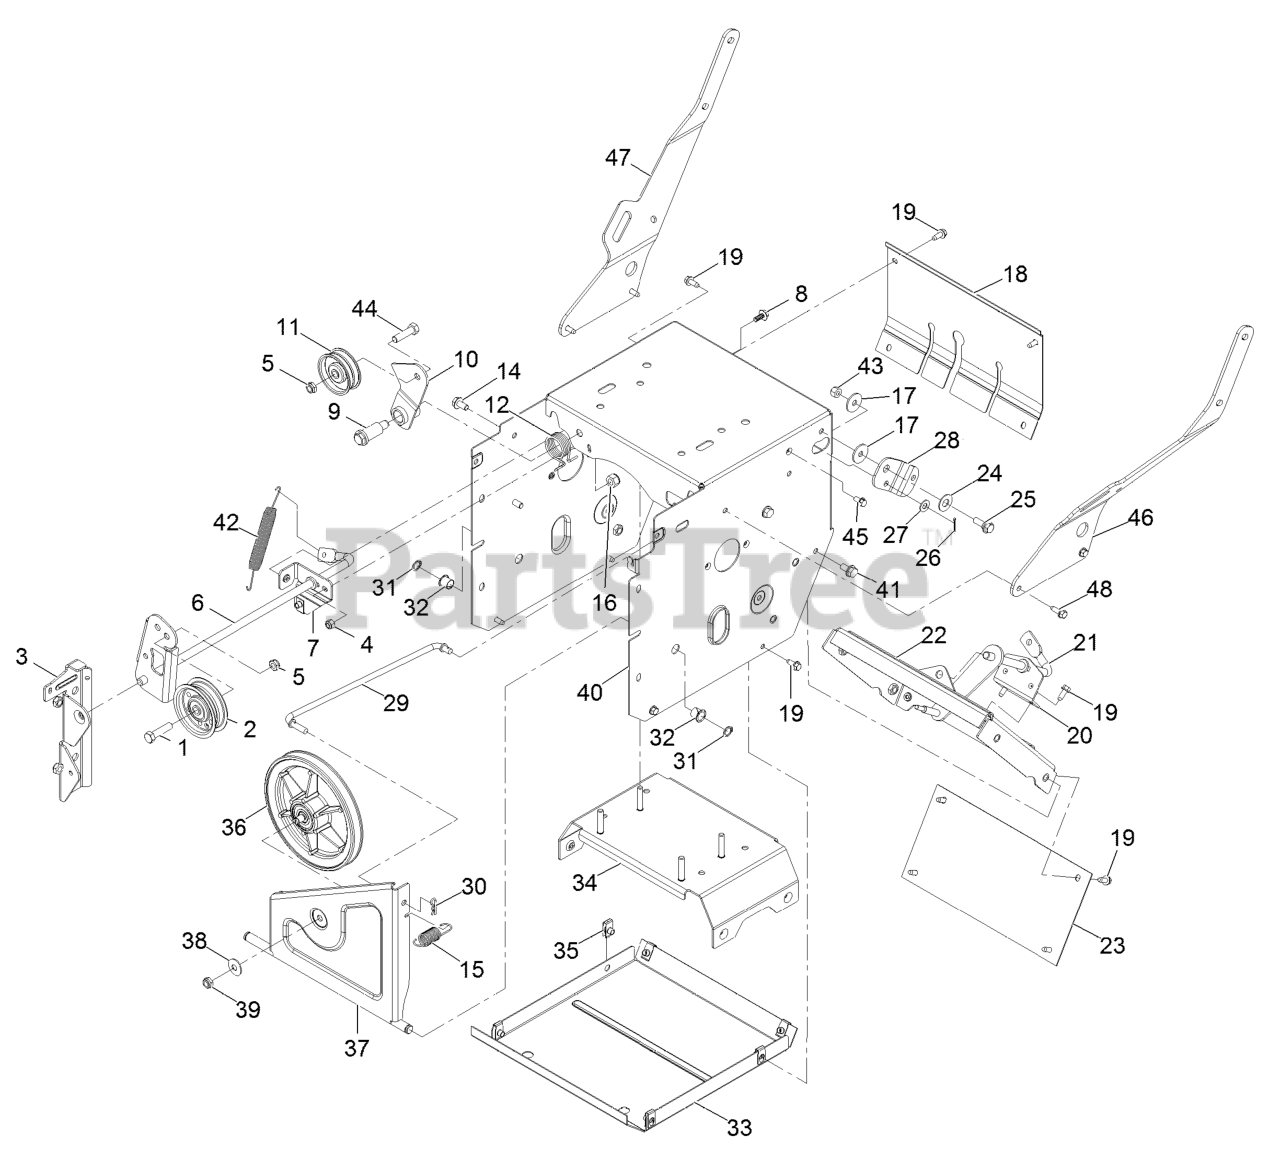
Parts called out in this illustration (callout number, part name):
1	SCREW-HH
2	PULLEY-IDLER
4	NUT-LOCK, NI
6	IMPELLER CLUTCH ASM
7	BRACKET-CLUTCH, IMPELLER
8	SCREW-HHF
9	BOLT-SHOULDER
10	ARM-IDLER, TRACTION
11	PULLEY-IDLER
12	SPRING-TORSION
14	SCREW-HHF
15	SPRING-EXTENSION
16	NUT-LOCK, NI
17	WASHER-PIVOT
18	COVER-UPPER
19	SCREW-HWH
20	BRACKET-ROD, SHIFT
21	LEVER-CONTROL, TRACTION
22	SHIFT PLATE ASM
23	COVER-LOWER
25	SCREW-SHOULDER
26	SCREW-HH
27	WASHER-PLAIN
28	BELLCRANK-DRIVE
29	LINK-CONTROL, SPEED
31	RING-RETAINING
32	BUSHING-NYLINER
33	PAN-BOTTOM
34	BRACE-FRAME
35	Nut-Retainer-Panel 1/4-20
36	PULLEY-TRACTION
37	BRACKET-WHEEL, FRICTION
38	WASHER-BELLEVILLE
39	NUT-HEX
40	TRACTION FRAME ASM
41	SCREW-HWHTF
43	NUT-LOCK, NI
44	SCREW-HH
45	SCREW-HWH
46	BRACE-HANDLE, LH
47	BRACE-HANDLE, RH
48	SCREW-HWH, THREAD ROLL
